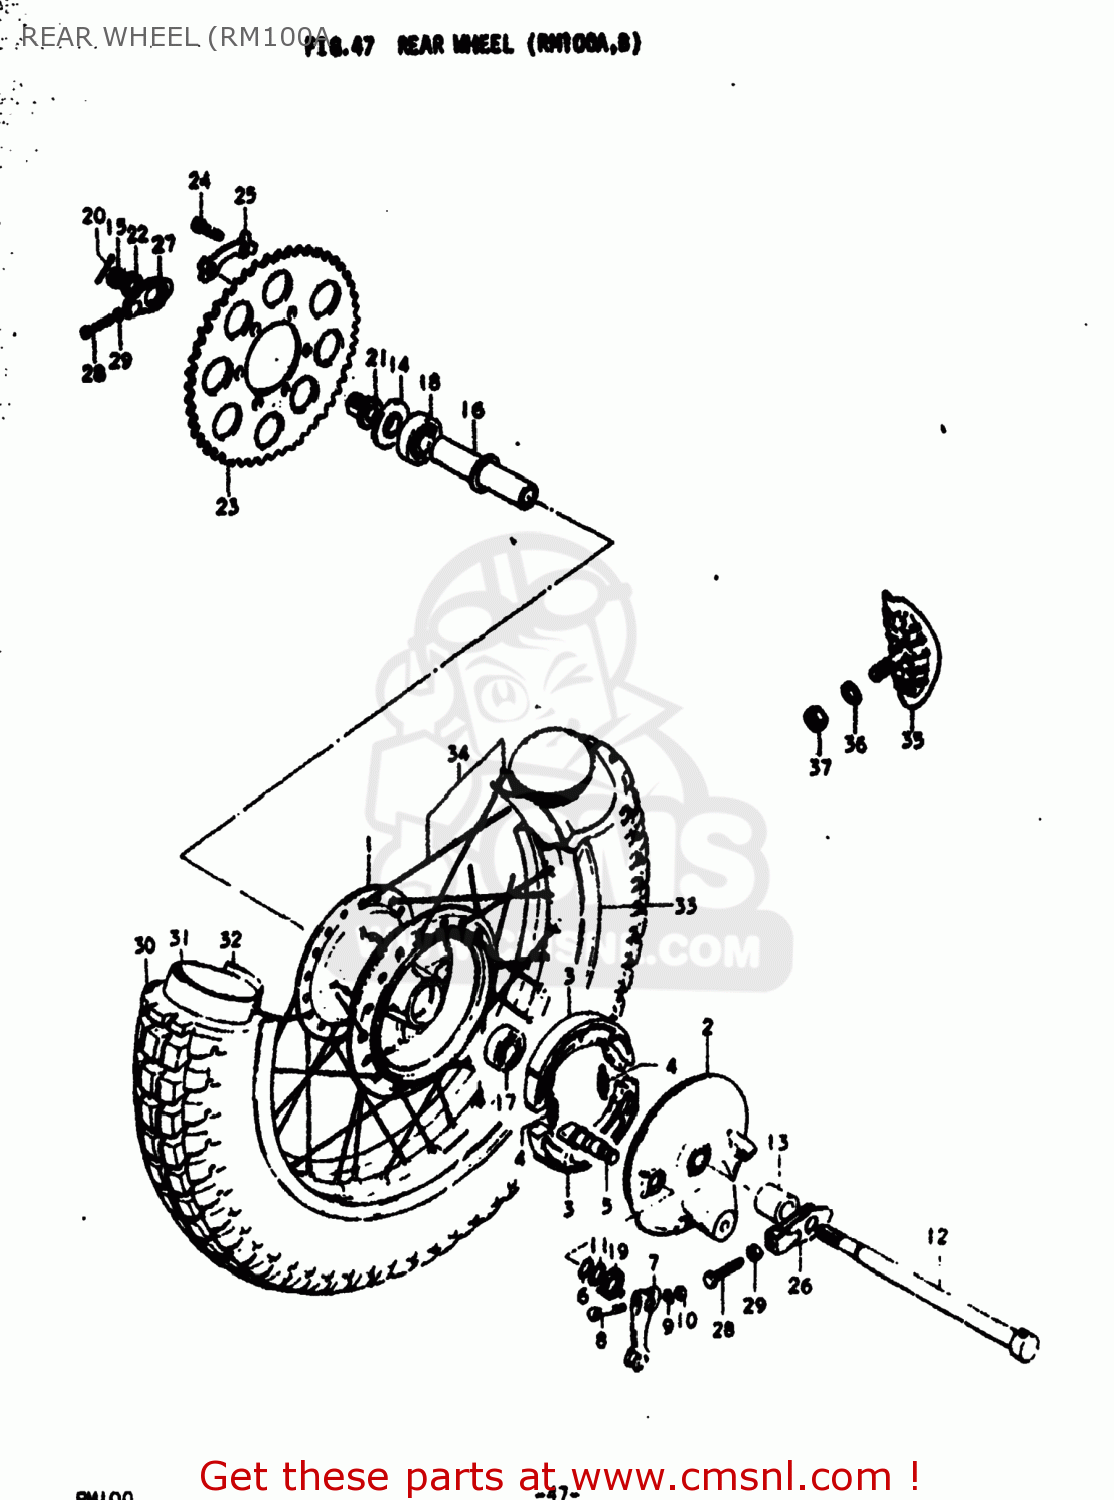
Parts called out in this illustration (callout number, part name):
1	HUB,REAR WHEEL
2	PANEL,REAR HUB
3	SHOE,BRAKE
4	SPRING(L:34)
5	CAM,FR BRAKE
6	O RING(D:2.5,ID:11.4)
7	LEVER,REAR BRAKE CAM
8	BOLT
9	WASHER
10	NUT
11	WASHER(12.5X20X1)
12	AXLE,REAR
13	SPACER(15.2X22X26)
14	SPACER,RR AXLE,L
15	NUT 12MM
16	SPACER,RR WHEEL HUB BEARING
17	BEARING
18	BEARING
19	SPRING
20	COTTER PIN
21	SPACER,CHAIN ADJUSTER,L
22	NUT
23	SPROCKET,REAR
24	BOLT(8X30)
25	WASHER
26	ADJUSTER,CHAIN
27	ADJUSTER,CHAIN
28	BOLT
29	NUT
30	TIRE
31	TUBE ASSEMBLY,WHEEL,INNER
32	PROTECTOR,WHEEL,INNER
33	RIM,REAR WHEEL
34	SPOKE SET,REAR
35	STOPPER,BEAD
36	WASHER
37	NUT
